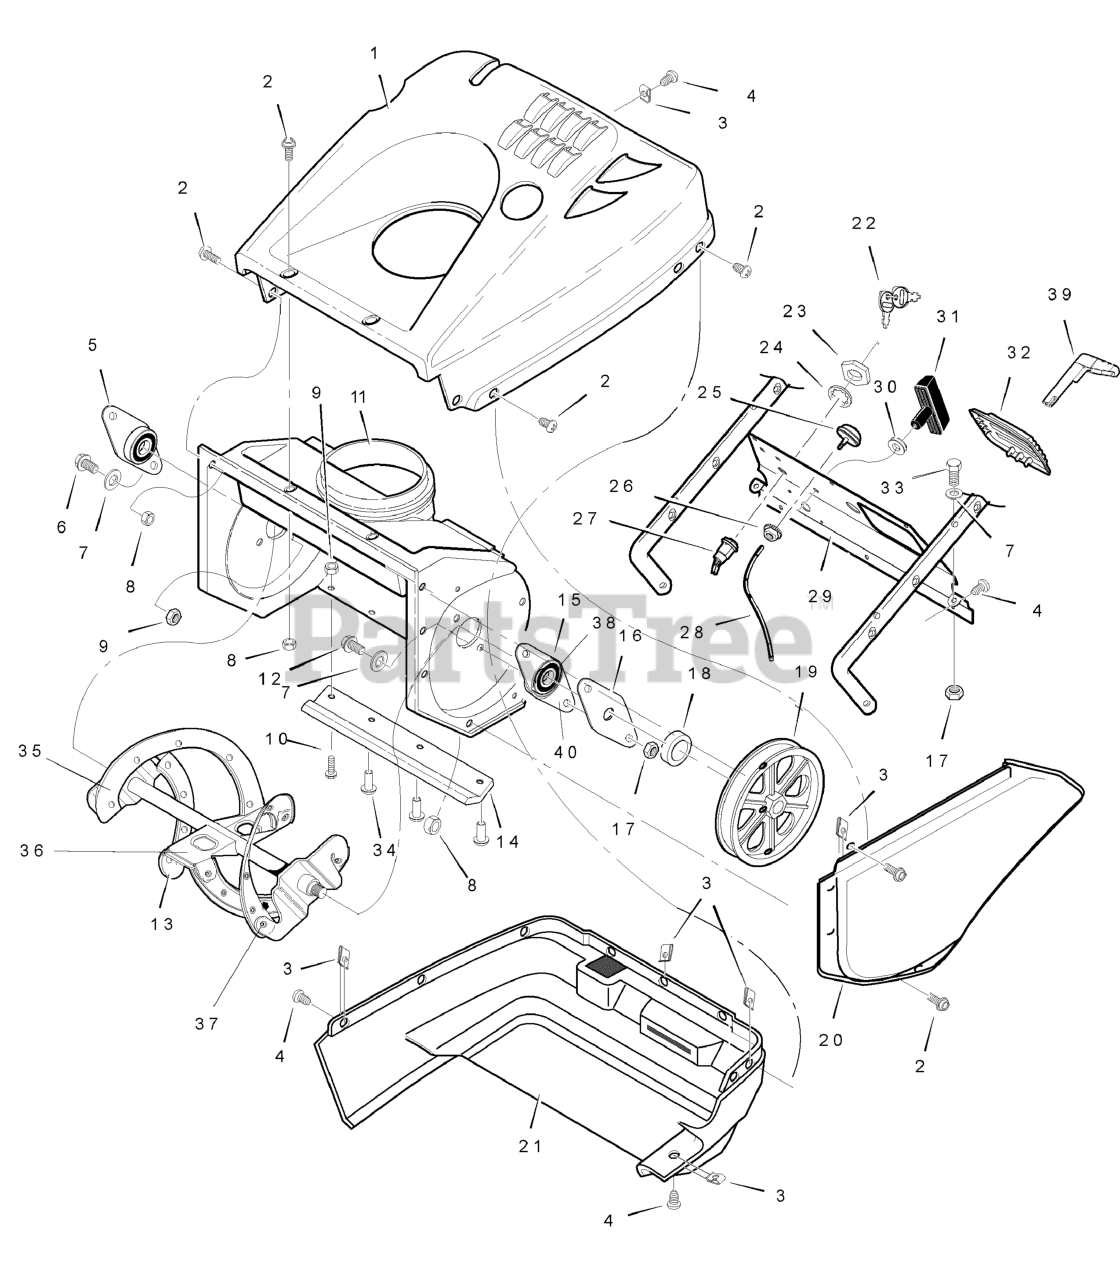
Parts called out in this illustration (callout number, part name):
1	COVER, TOP
2	SCREW, #10-24 X 0.50
3	NUT, 1/4-10 SPEED J-TYPE
4	SCREW, 1/4-14 X 0.75
5	FLANGE BEARING
6	SCREW, 1/4-20 X 1.00
7	WASHER, FLAT
8	NUT, #10-24 HEX CONTROL LOCK
9	NUT, 1/4-20 HEX CONTROL LOCK
10	SCREW, 1/4-20 X 0.75
11	AUGER HOUSING ASSEMBLY
12	SCREW, 1/4-20 X 0.63
13	AUGER ASSEMBLY, COMPLETE
14	BLADE, SCRAPER
15	SF BEARING & PLATE ASSEMBLY
16	LT PLATE, RETAINER BEARING
17	NUT, 1/4-20 HEX CONTROL LOCK
18	SPACER, SLEEVE
20	COVER, BELT
21	COVER, BOTTOM
22	SET, Key
23	NUT, 5/8-32
25	PRIMER-CARBURETOR
26	NUT, 1/-20 HEX KEPS
27	SWITCH, IGNITION 45 DEG.
28	HOSE, PRIMER 9.5"
29	PANEL, CONTROL
30	GROMMET & WASHER, ROPE
31	GRIP, Starter Rope
32	PANEL, ACCESS SPARK PLUG
33	SCREW, 1/4-20 X 1.25
34	RIVET, OFFSET
35	BLADE, AUGER
36	BLADE, CENTER
37	RIVET, OFFSET
38	BEARING, BALL
39	KNOB-CHOKE SHAFT
40	RETAINER, BEARING
